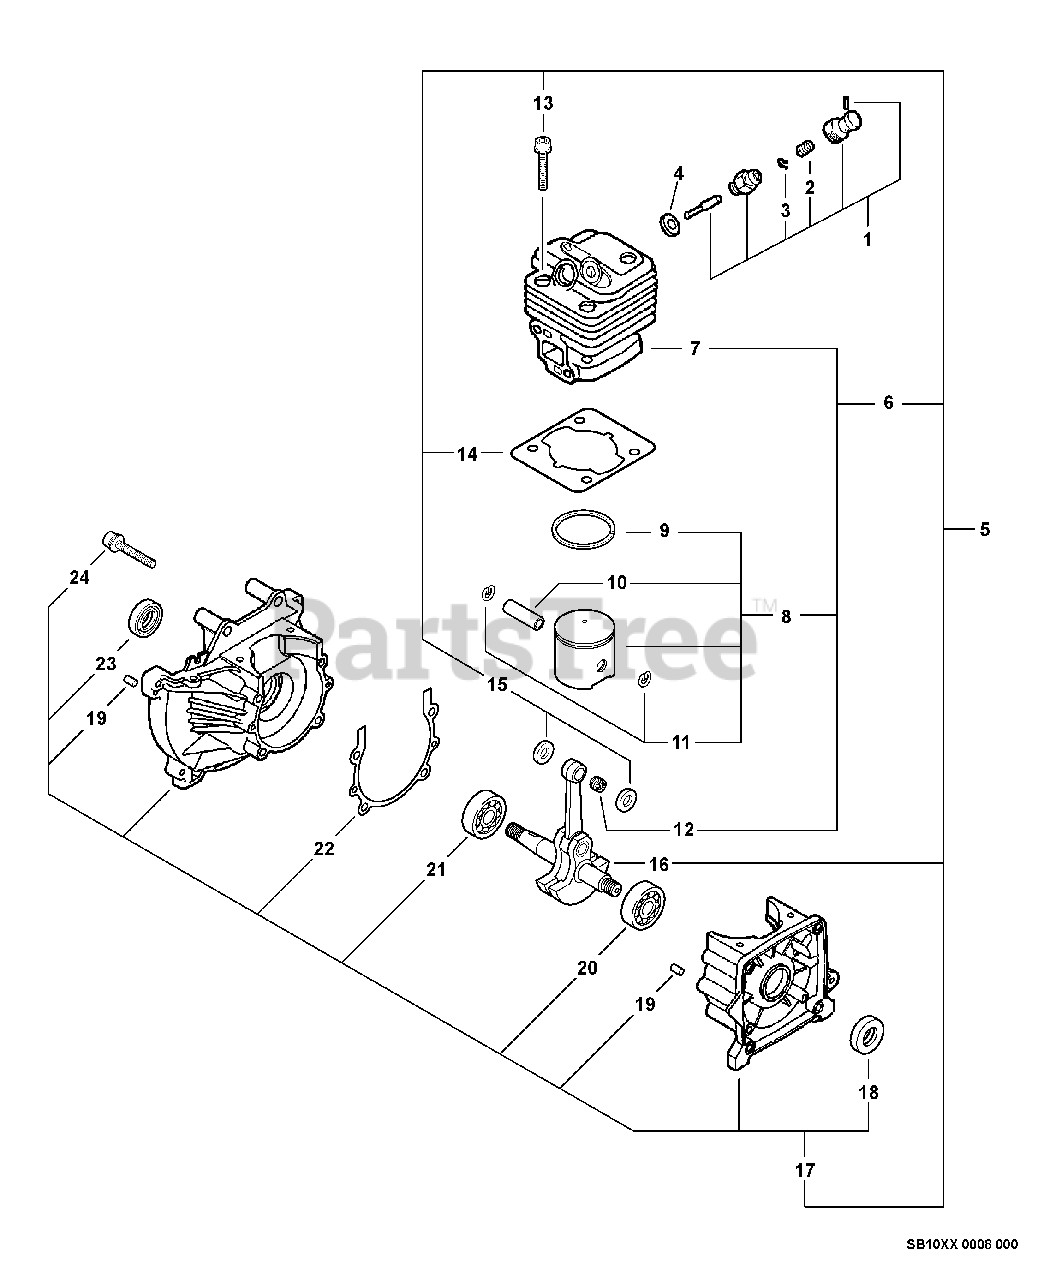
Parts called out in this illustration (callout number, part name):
1	DECOMPRESSION ASSY
4	WASHER
5	SHORT BLOCK
6	CYLINDER/PISTON KIT
7	CYLINDER
8	PISTON KIT
9	RING, PISTON
10	PIN, PISTON
11	RING, RETAINING - 8
12	BEARING, NEEDLE
13	SCREW - 5X20
14	GASKET, CYLINDER
15	WASHER - 10
16	CRANKSHAFT ASSY
17	CRANKCASE KIT
18	SEAL, OIL
19	PIN - LOCATING
20	BEARING, BALL - 6201
21	BEARING, BALL - 6202
22	GASKET, CRANKCASE
23	SEAL, OIL
24	SCREW - 5X35
